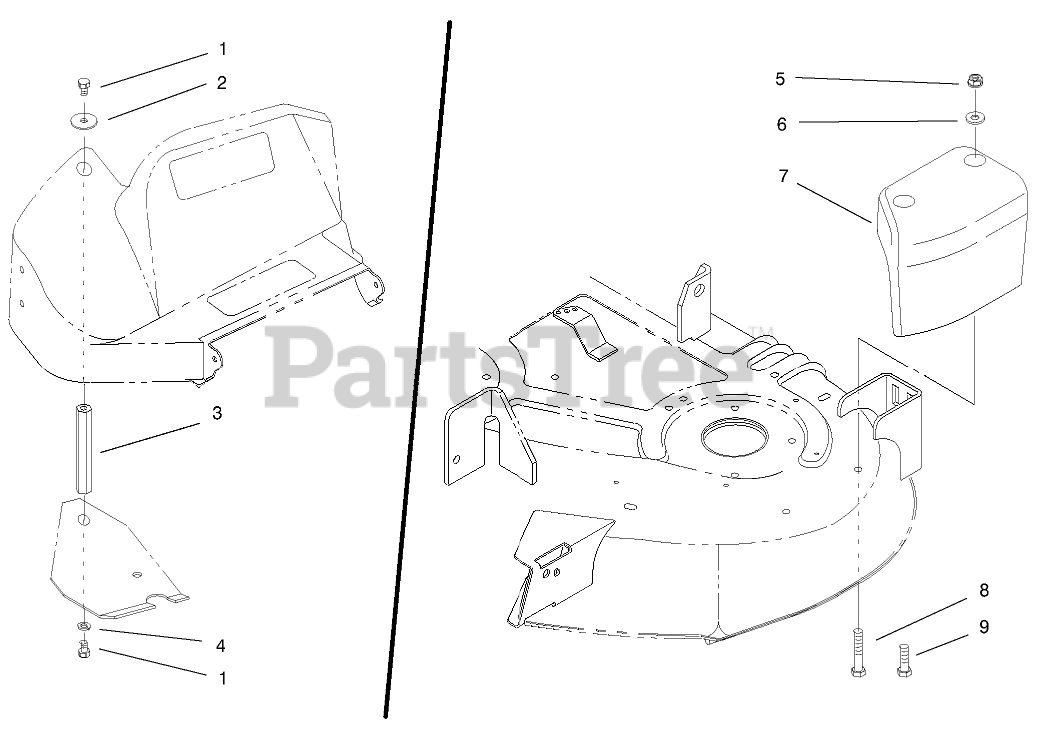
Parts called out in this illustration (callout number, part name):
1	Screw-HH (Only On:79448)
2	Washer-Flat (OnlyOn: 79448)
3	Shaft-Vac Bagger(Only On: 79448)
4	Washer-Lock (OnlyOn: 79448)
5	NUT-LOCK, NI
6	WASHER-FLAT
7	WEIGHT
8	SCREW-HH
9	SCREW-HH
